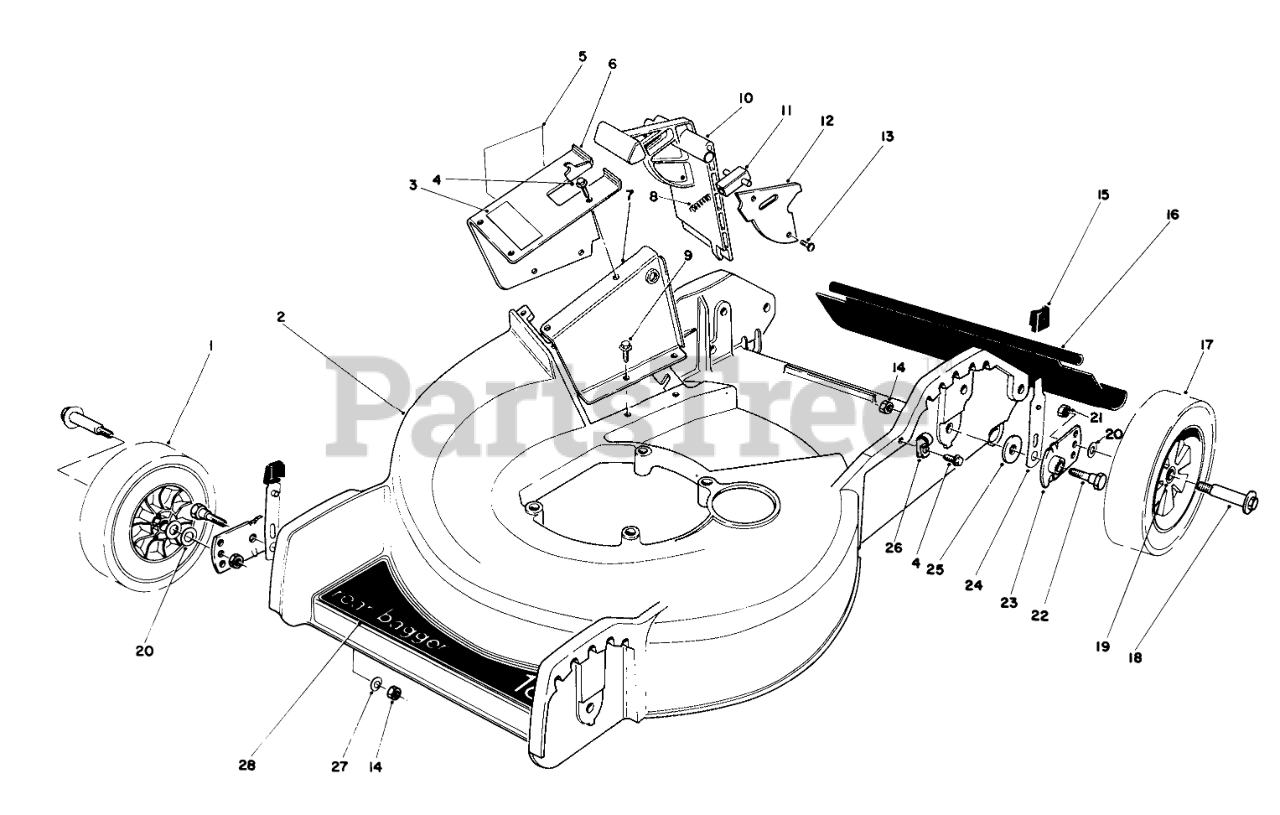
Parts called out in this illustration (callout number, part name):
1	Wheel & Tire Assembly (Incl. Ref. #19)
2	Housing
3	Decal-Door
4	SCREW
5	DECAL-DANGER
6	Tunnel-Outer (Incl. Ref. #3 & 5)
7	Tunnel-Inner
8	SPRING-COMPRESSION, LATCH
9	SCREW
10	Door Mulching
11	Door Latch
12	Cover Door
14	NUT-LOCK, NI
15	KNOB-ARM
16	SHIELD - TRAILING
17	Wheel & Tire Assembly (Incl Ref. #19)
18	BOLT-WHEEL
19	BUSHING
20	WASHER
21	Nut
22	5/16-18 PIVOT SCREW
23	PIVOT ARM ASSY
24	SPRING ARM ASM
25	PIVOT WASHER
26	CLAMP-NYLON
27	WASHER-BELLEVILLE
28	DECAL-DECK
